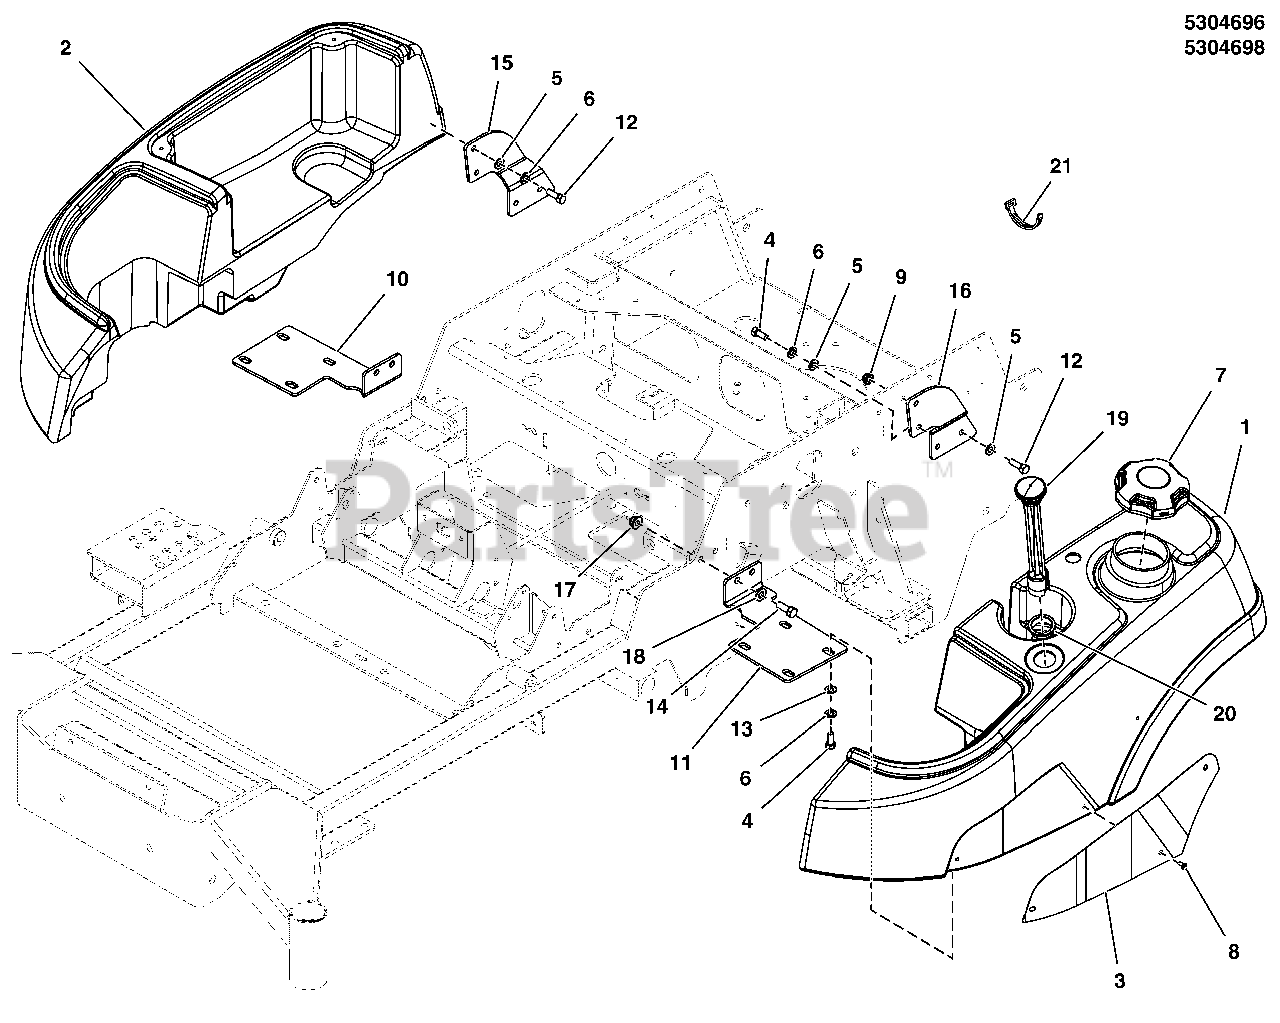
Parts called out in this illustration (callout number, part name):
1	TANK, FUEL, 5.25 GAL, LH
2	TANK, FENDER, CONZ, RH
3	PLATE, FUEL TANK BADGE
4	CAPSCREW, Hex Head, 5/16-18 x 3/4
5	WASHER, Flat, 5/16
6	WASHER, Flat
7	CAP, Fuel
8	CAPSCREW, Button Allen Head, #10-24 X 3/8
9	NUT, Flange Nylock, 5/16-18
10	PLATE, TANK MOUNT, RIGHT - BLK
11	PLATE, TANK MOUNT, LEFT - BLK
12	CAPSCREW, Hex Head, 5/16-18 x 1 1/4
13	WASHER, 5/16" GD.9 FLAT
14	CAPSCREW, Hex Head, 3/8-16 x 1
15	PLATE, FUEL TANK MOUNT - REAR, RH - RED
16	PLATE, FUEL TANK MOUNT - REAR, LH - RED
17	NUT, Hex Flange, Nylock, 3/8-16
18	WASHER, .406
19	GAUGE, FUEL LEVEL, 9.0"
20	GROMMET, FUEL GAUGE (SV)
21	TIE, SELF-LOCKING, 8"
